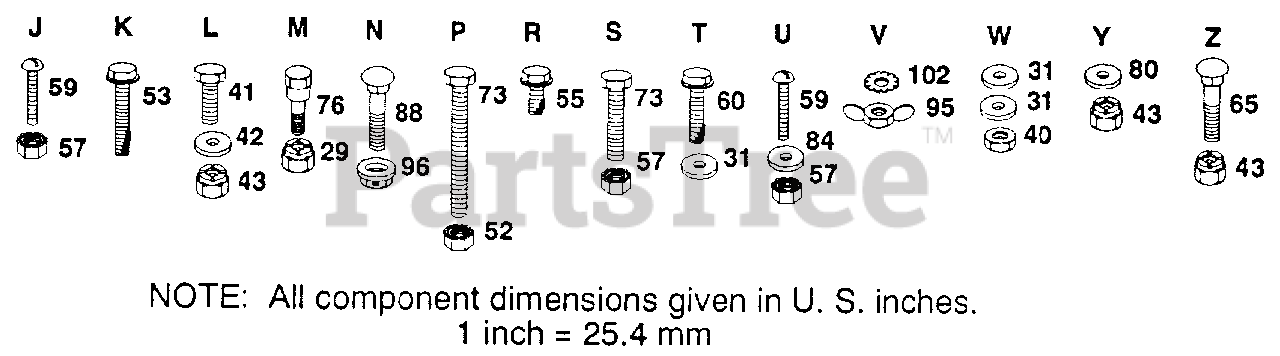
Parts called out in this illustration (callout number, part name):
31	WASHER PM
42	WASHER
52	NUT
53	SCREW LT
59	SCREW
60	SCREW HEX CRT
65	BOLT
80	WASHER
84	WASHER
88	BOLT
102	LOCKWASHER GT
